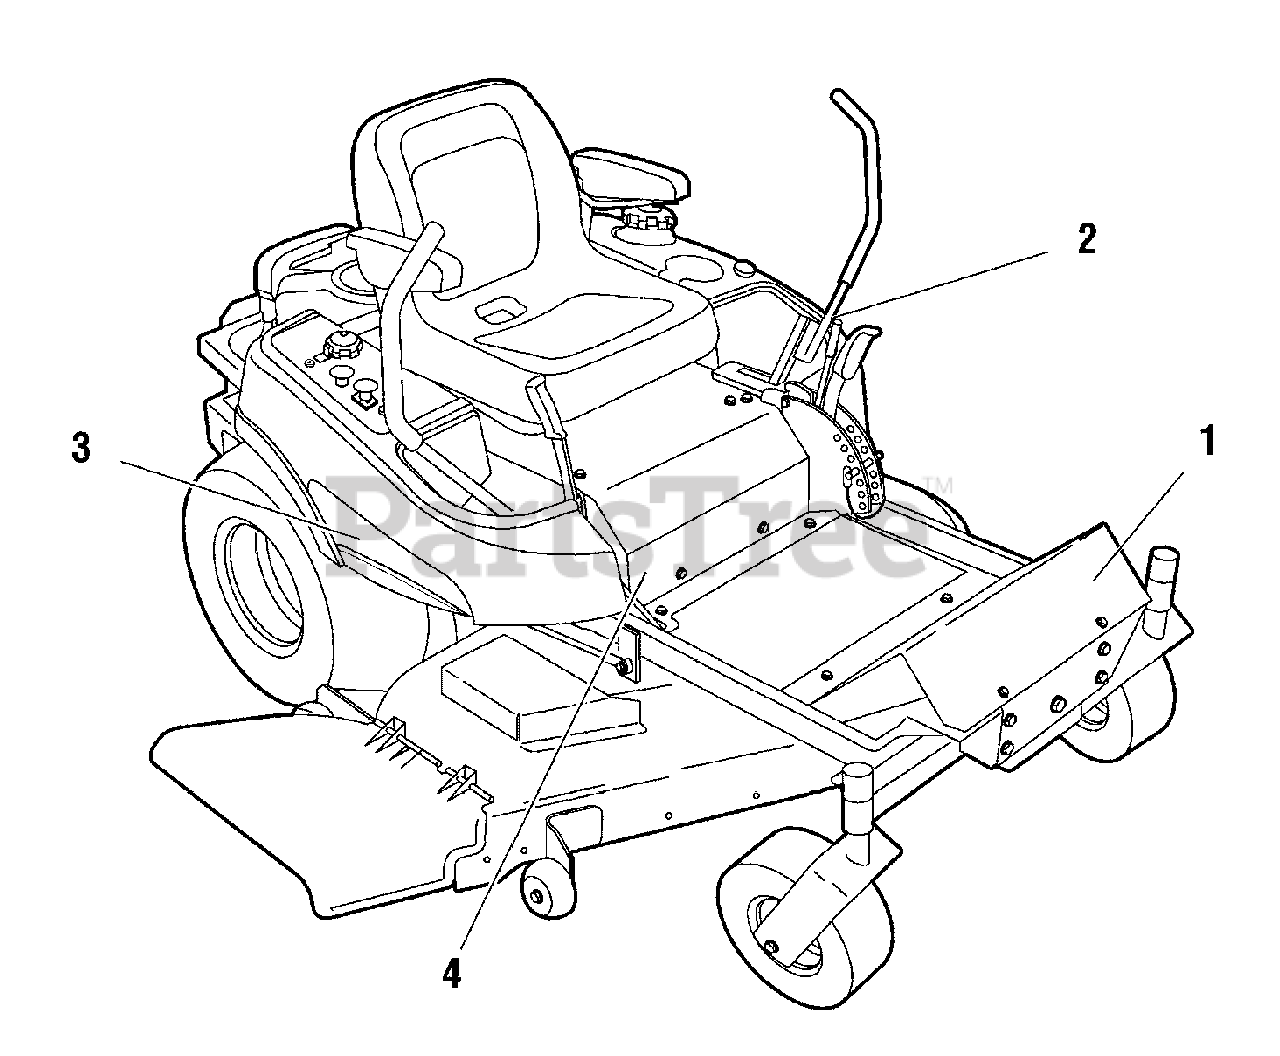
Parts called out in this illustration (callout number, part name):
1	DECAL, MASSEY STRIPE
2	DECAL, LH TANK
3	DECAL, RH TANK
4	DECAL, ZT2450
4	DECAL, ZT2452
